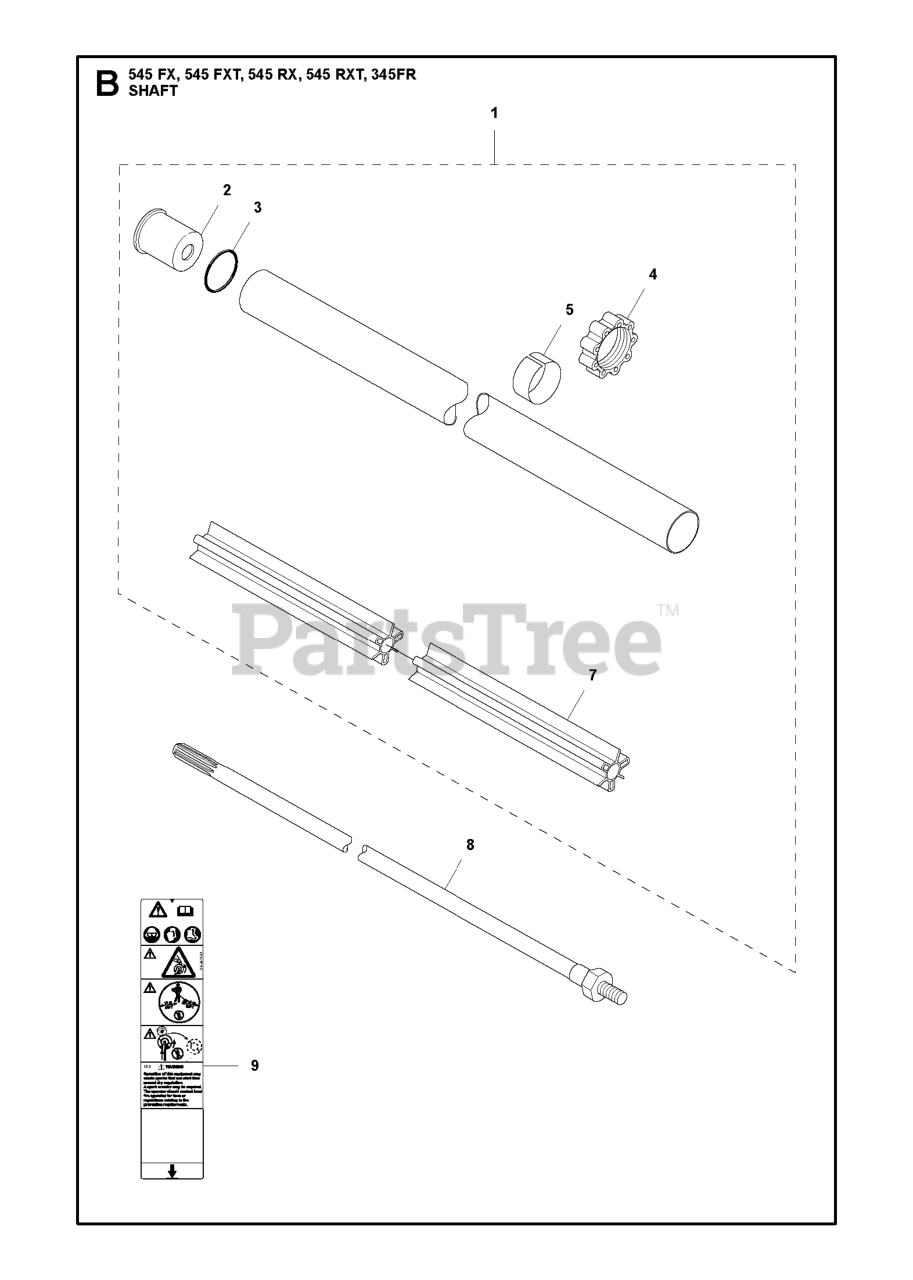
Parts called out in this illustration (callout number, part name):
1	TUBE ASSY
2	SPACER SLEEVE
4	MOVEMENT LIMITER
5	%BAND
7	BEARING SHAFT
8	DRIVE SHAFT
9	LABEL WARNING TRIMMERS AND BRU
